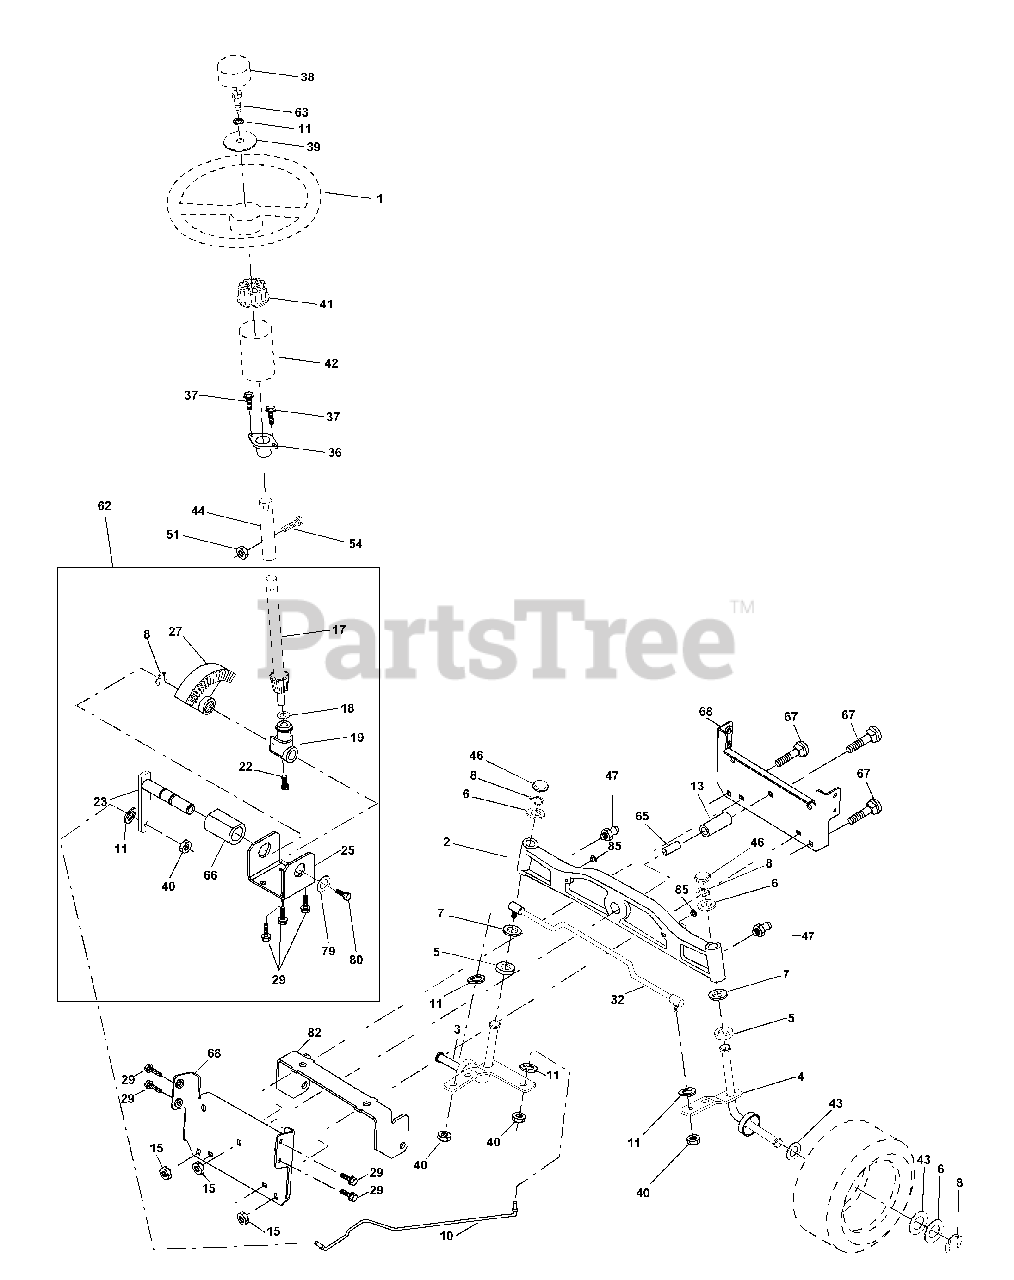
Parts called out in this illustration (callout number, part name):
1	Wheel Steering
2	Axle Cast LT Machined
3	Spindle Asm LH
4	Spindle Asm RH
5	Bearing Race Thrust Harden
6	Washer 25/32 X 1-5/8 X 16 Ga
7	Washer 27/32 X 1-1/4 X 16 Ga
8	Ring Klip #t5304-75
11	Washer Lock Hvy Hlcl Spr 3/8
13	Spacer Brg Axle Front
15	Nut Hex Flange Lock
17	Shaft Asm Strg
18	Washer Thrust 515 x 750 x 033
19	Support Shaft
22	Screw Hex Wshhd Torx
23	Shaft Asm Pittman
25	Bracket Steering
27	Gear Sector
29	Screw 3/8-16x3/4
32	Rod Asm Tie Ball Joint Noram
36	Bushing Strg
37	Screw
38	Insert Cap Strg Wh
39	Washer 13/32 x 1-1/20 x 11 Ga.
40	Lock nut
41	Adaptor Wheel Strg
42	Boot Steering
43	Washer 25/32 X 1 1/4 X 16 Ga
44	Extension Steering Non-Adjust
46	Cap Spindle Fr Top Blk
47	Fitting Grease
51	Nut Crown Lock 5/16-18
54	Bolt Fin Hex 5/16-18 Unc x 1 1/4
62	Kit, Steering Assembly Svc
63	Bolt Fin Hex 3/8-16 Unc x 1 Gr 5
65	Spacer Brace, Axle
66	Bearing Arm Pittman
67	Bolt Rdhd Sqneck 3/8-16 x 2-1/4
68	Axle, Brace
79	Washer 13/32 x 1 1/4 x 12 Ga
80	Bolt Hex Nylon 3/8-16 x 3/4
82	Bracket Susp Chassis Front 15"
